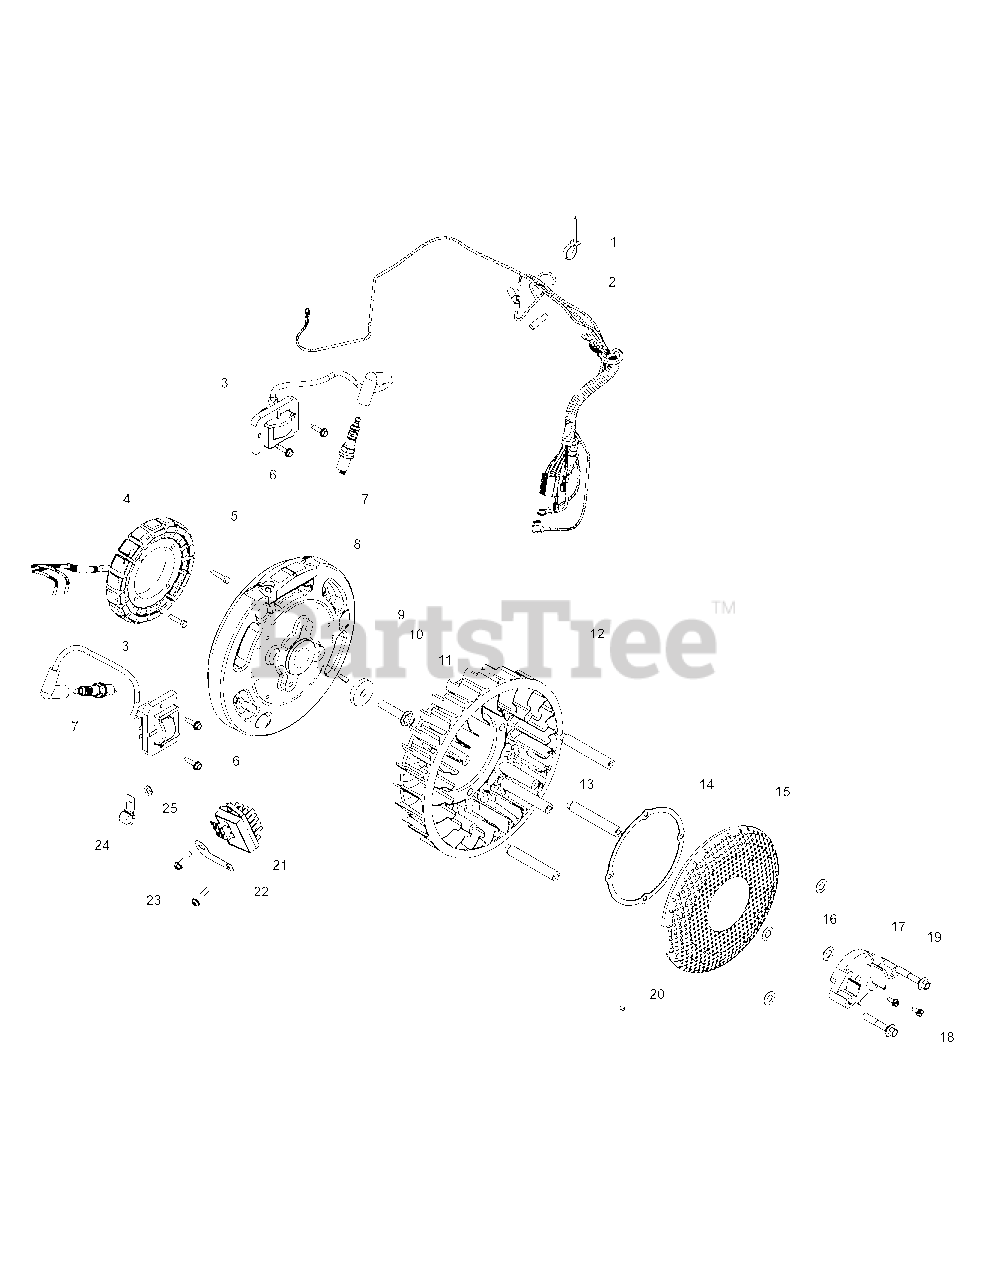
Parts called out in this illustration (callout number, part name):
2	Harness, Wiring Assembly
3	Kit, Module Ignition (CDI Fixed)
4	Kit, 25 Amp Stator Ass’y
5	Screw, Thd Frm M5x0.8x25
6	Screw, Flg Thd Frm M5x0.8x20
7	Plug, Spark
9	Key, 3/16" X 5/8"
10	Washer, Flat 13/32"
11	Screw, Flg M10x1.5x45
12	Fan
14	Ring, Support
15	Screen, Grass
16	Washer, Spring 10 Mm
17	Adapter, Drive Shaft
18	Screw, Wsh HD Tap #8-18x1/2"
19	Screw, Flg M8x1.25x45
20	Screw, Skt Set #10-24x1/4"
21	Regulator, Rectifier
22	Bracket, Ground Strap
23	Screw, Hex Flange Hi-Lo
24	Clip, Cable
25	Washer, Flat 1/4"
